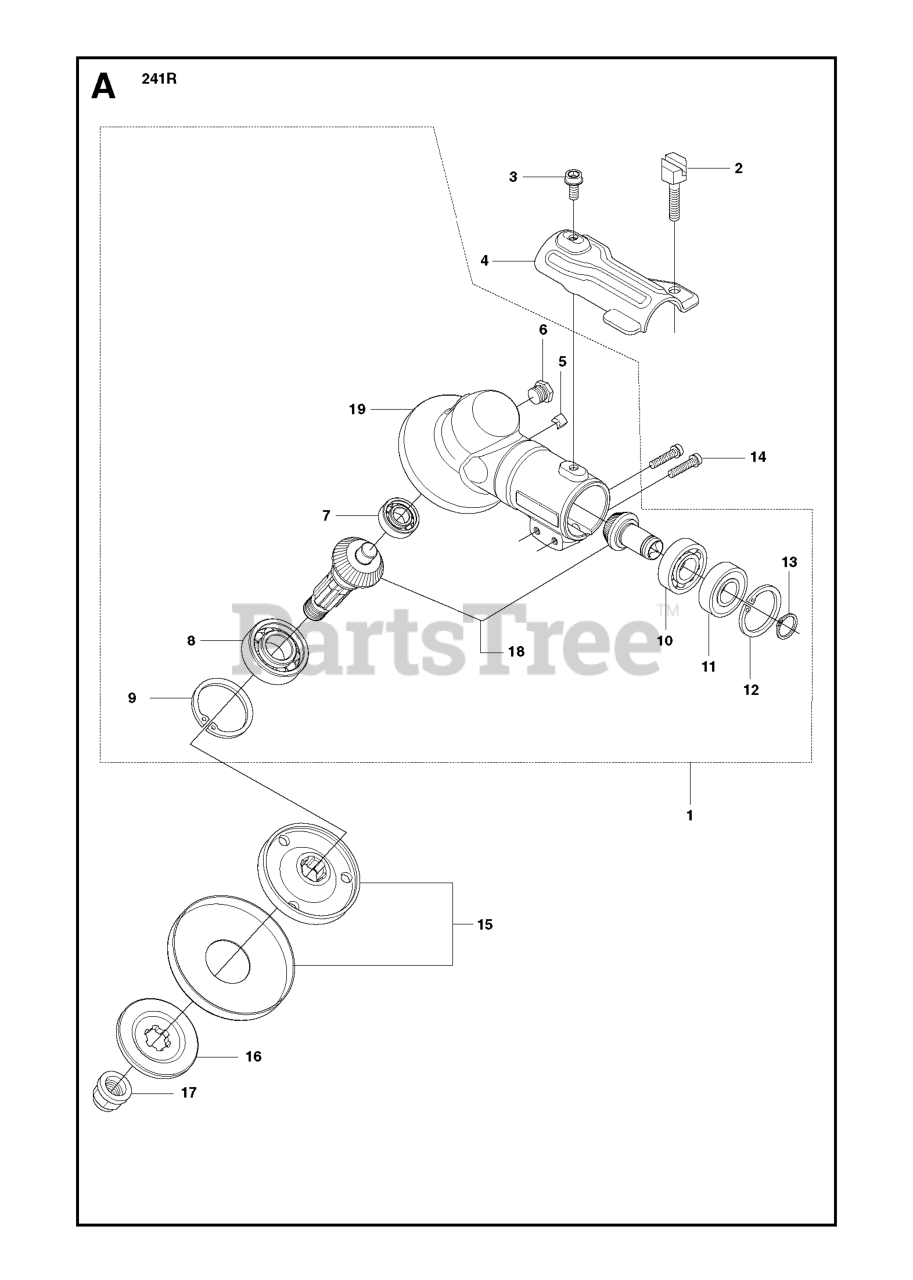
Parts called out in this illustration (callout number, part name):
1	GEAR CASE SET
3	SCREW
4	RP HOLDER
7	BALL BEARING 24X9X1/609ZR
8	BALL BEARING
9	RETAINING RING
10	BALL BEARING
11	BALL BEARING
12	RETAINING RING SGH 28
13	SEEGER CLIP
15	RP CARRIER
16	RP FLANGE
17	BLADE NUT
18	SPARE PARTS KIT
